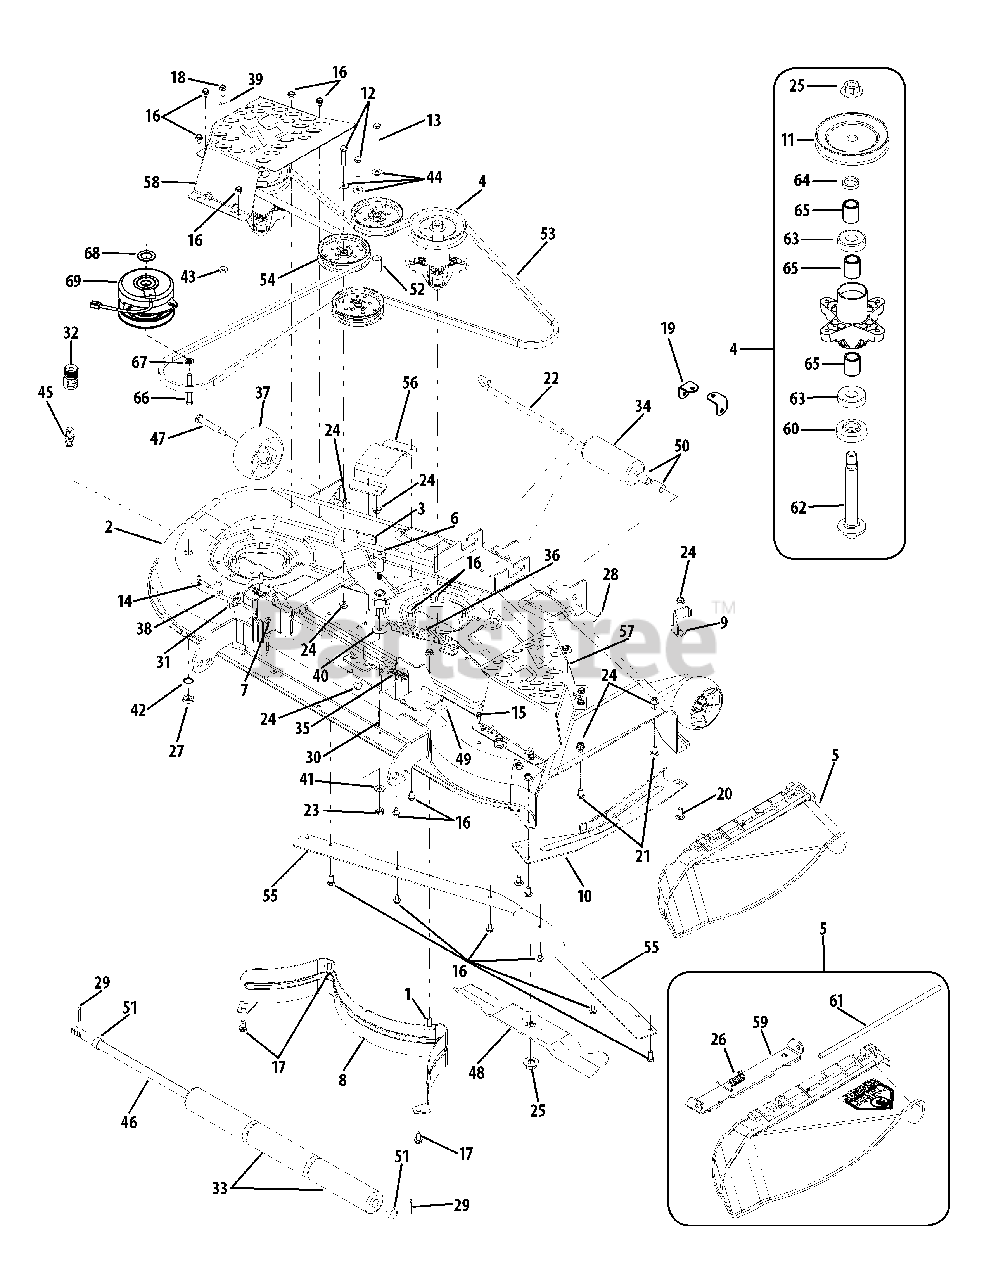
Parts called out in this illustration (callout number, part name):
1	Carriage Bolt 3/8-16 x 1" Lg. (Gr. 5)
4	Spindle Assembly
5	Discharge Chute Ass’y
6	Bolt, Shoulder
10	Finger Guard
11	V-Type Pulley, 5.39
12	Hex Screw 3/8-16 x 1.75
13	Hex Screw 3/8-16 x 3.0
14	Hex Bolt 5/16-18 x 1.25
15	Hex Wash S-Tapp Screw 1/4-20 x .50
16	Hex Wash HD AB Screw 5/16-18 x .75
17	Hex Wash Screw. 3/8-18 x .75
18	Hex Wash Screw. 5/16-18 x .875
21	Carriage Screw 3/8-16 x .75
22	Roller Pin .5 x 10.06
23	Hex Lock Nut 7/16-14
24	Hex Ins. Flg L-Nut 3/8-16
25	Hex Flange Nut 5/8-18
26	Torion Spring
27	Hex Nut M16-1.5 DIN 936
28	Cotter Pin 3/32 x 1.0
29	Cotter Pin 5/32 x 1.25
30	Cotter Pin 1/8" Dia x 1.25
31	Deck Adjustment Gear
32	Water Nozzle Adaptor
33	Deck Roller, 7.895
34	Front Roller
35	Compression Spring .535 x 1.751
36	Extension Spring .94 x .04609
37	Deck Ball Wheel, 5.0
38	Lockwasher 5/16
39	Flat Washer .344 x .688 x .065
40	Flat Washer .442 x 1.39 x .06
41	Cupped Washer .45 x 1.0 x .062
42	Lockwasher
43	Flat Washer .407 x .812 x .135
44	Flat Washer .38 x .93 x .11
45	Port, Water
46	Shaft, .75 x 26.893
47	Shoulder Screw, 1/2 Diameter x 2.5
48	Blade 18.5" Lg.
49	Deck Re lease Pin
50	Spacer .55 x .75 x 1.125
51	Spacer .82 x 1.0 x .53
52	Spacer .38 x .9 x 1.313
54	Idler Pulley w/Flange 4.25 Dia
59	Chute Mounting Bracket
60	Spacer .79 x 1.82 x .55
61	Hinge Pin
62	Spindle Shaft 6.95 Lg.
63	Ball Bearing 20 x 47 x 14:6204:DS
64	Spacer .79 x 1.25 x .175
65	Spacer .080 x 1.10 x 1.322" Lg.
66	Hex Hd Cap Screw. 7/16-20 x 3.50
67	Lockwasher 7/17
68	Flat Washer 1.03 x 1.620 x .095
69	Electric PTO Clutch
